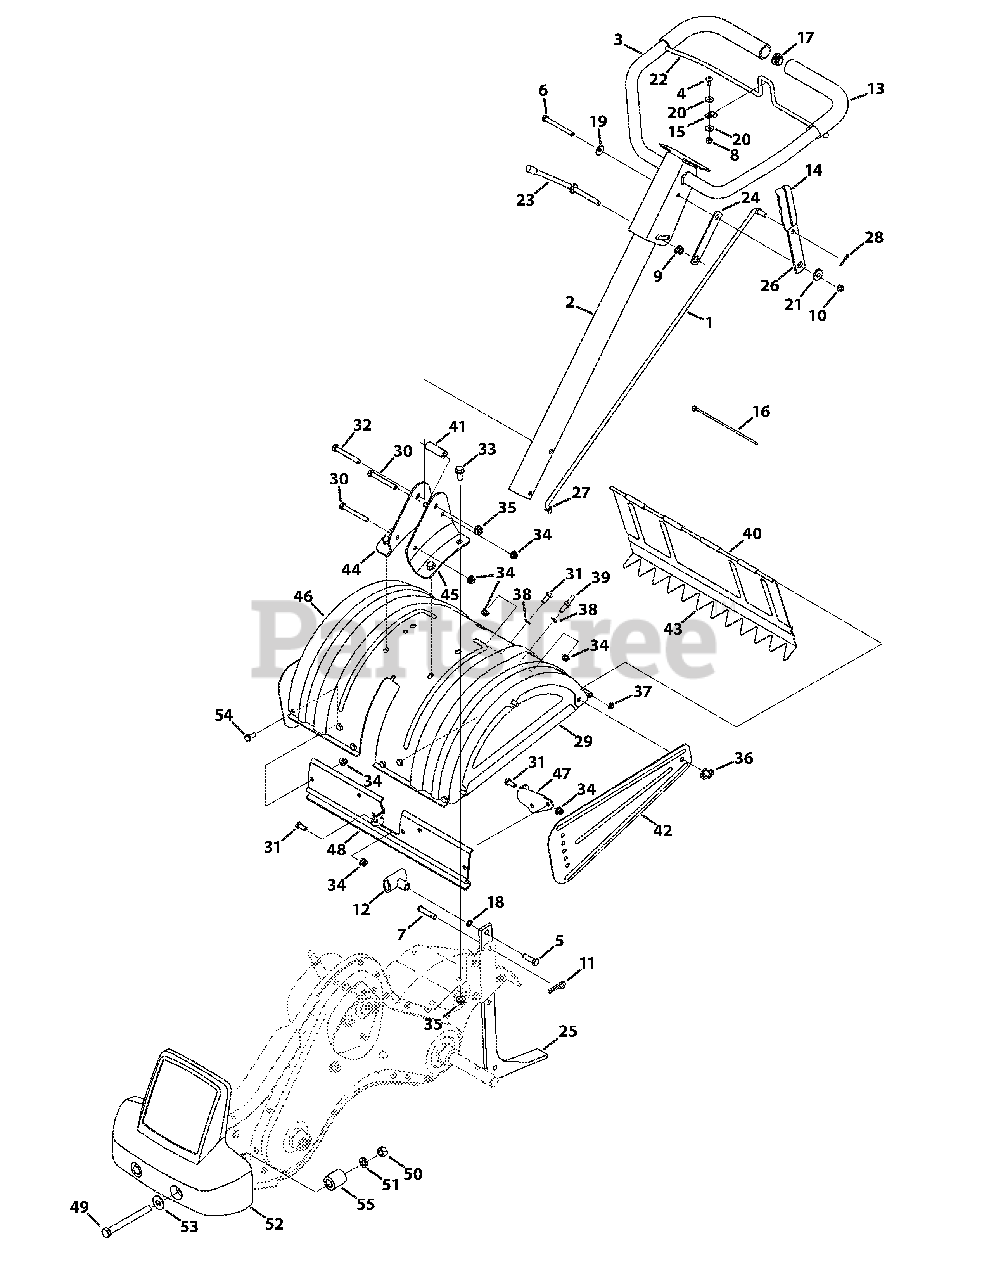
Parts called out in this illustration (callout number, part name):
1	Shift Rod
2	Lower Handle Tube Assembly - Black
2	Lower Handle Tube Assembly - Red
3	Upper Handle Assembly - Black
3	Upper Handle Assembly - Red
4	Screw, 1/4-20 x 0.625
5	Hex Head Screw, 3/8-16:1.25
6	Hex Head Screw, 5/16-18 x 3.25
7	Clevis Pin, .375 X 1.75
8	Hexlock Nut, 1/4-20
9	Flangelock Nut, 3/8-24
10	Hexlock Nut, 5/16-18
11	Cotter Pin, .125 X 1.75 internal
12	Small Tee Knob
13	Foam Grip, .970 x 11.0
14	Grip, .1875 x 1.00
15	Battery Clamp, 5/16
16	Cable Tie, 8.5 LG
17	End Plug
18	Washer, Flat, .385 x .620 x .033
19	Washer, Bell, .340 x .872 x .060
20	Washer, Flat, .260 x .720 x .060
21	Spacer, Shoulder, .50 x .190 x .360 LG
22	Clutch Bail
23	Handle Adjustment Crank
24	Hex Nut Retainer Bracket
25	Tiller Depth Control
26	Shift Rod Lever - Black
26	Shift Rod Lever - Red
27	Washer, Rubber, .33 ID x .87 OD x .125
28	Cotter Pin, .072 x 1.12 LG
29	End Cover Assembly - Black
29	End Cover Assembly - Red
30	Hex Head Screw, 5/16-18 x 2.75
31	Hex Head Screw, 5/16-18 x .75
32	Hex Head Screw, 3/8-16 x 2.75
33	Hex Head Flange, 3/8-16 x .875
34	Flangelock Nut, 5/16-18
35	Flangelock Nut, 3/8-16
36	Wing Nut, 5/16-18 W/ Bell Washer
37	Speed Nut Cap, 1/4 ROD
38	Washer, Flat, .344 x .62 x .033
39	Screw, Hex, 5/16-18 x .75
40	Tiller Flap Rod
41	Spacer, .322 x .625 x 2.00
42	Side Shield - Black
42	Side Shield - Red
43	Rear Tine Shield - Black
43	Rear Tine Shield - Red
44	RH Handle Mount Bracket - Black
44	RH Handle Mount Bracket - Red
45	LH Handle Mount Bracket - Black
45	LH Handle Mount Bracket - Red
46	Tine Shield - Black
46	Tine Shield - Red
47	FRT Tine Shield Bracket
48	FRT Tine Shield Spacer Bracket
49	Hex Head Screw, 1/2-13 x 5.00
49	Hex Head Screw, 1/2-13 x 5.50
50	Hex Nut, 1/2-13
50	Hex Nut, 1/2-20
51	Washer, Lock, 1/2
52	Counterweight
53	Washer, Flat, 1/2 x 1.25 x .100
54	Hex Head Screw, 5/16-18 x 1.00
55	Hub, .636 ID x 1.00 OD x .94
